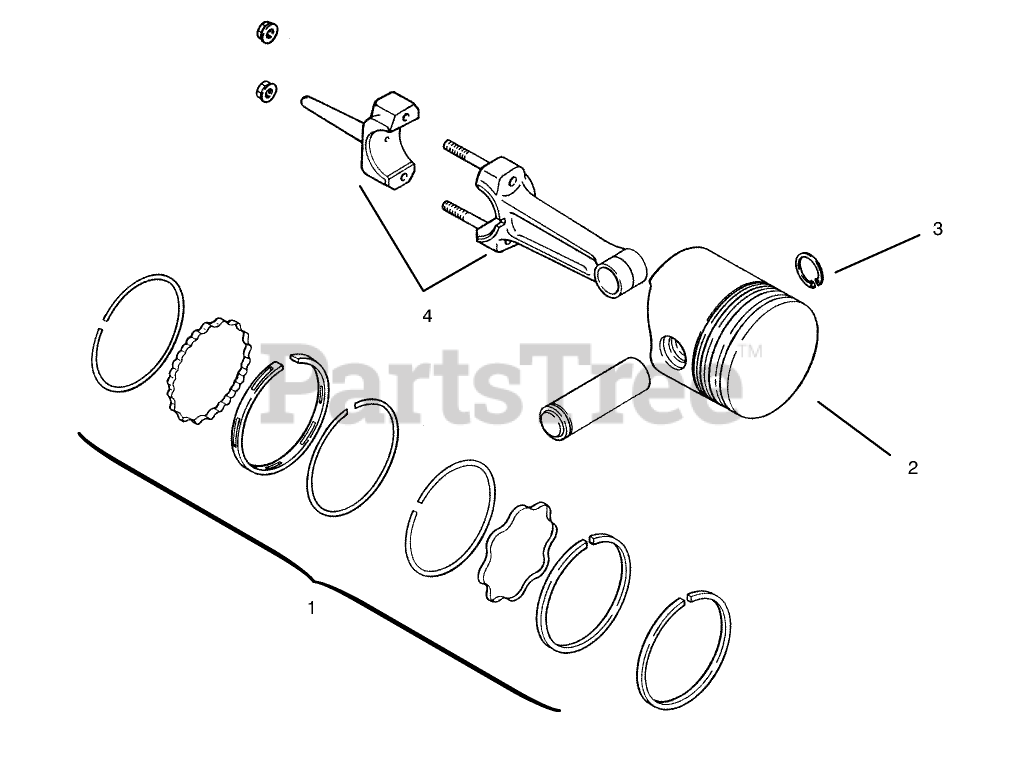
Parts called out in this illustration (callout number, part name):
1	Set-Ring STD .003 14hp
2	Piston-Ring Set STD 14hp
4	Rod-Connecting STD
